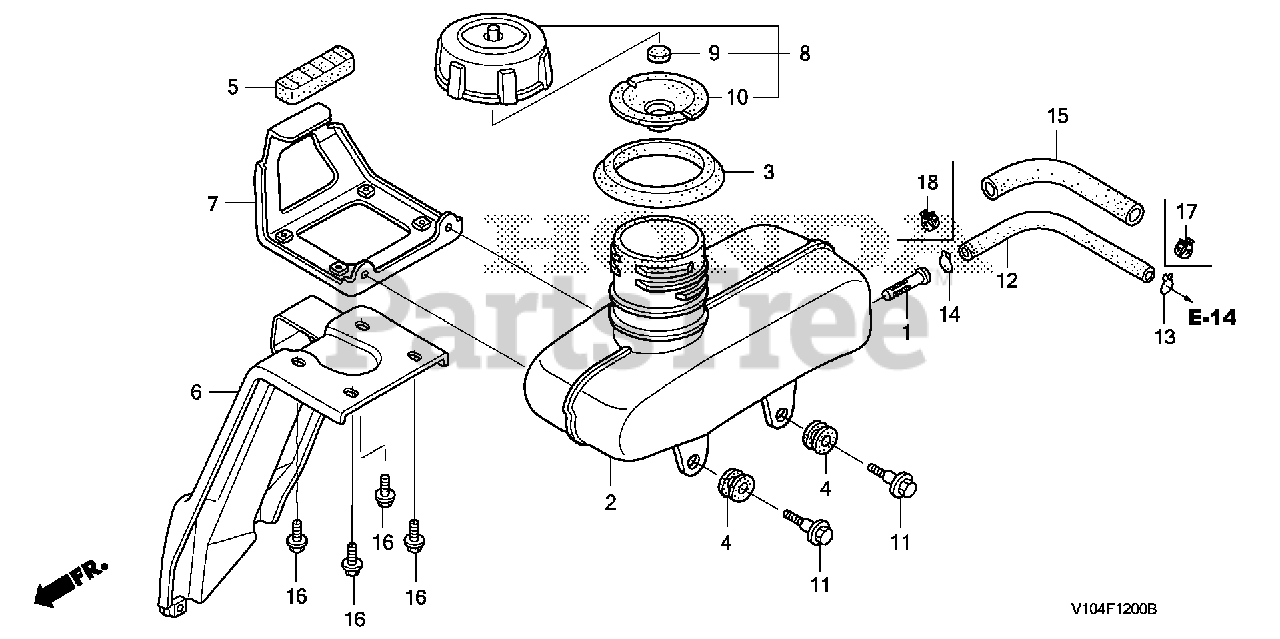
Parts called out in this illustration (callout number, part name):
1	FILTER, FUEL
2	TANK, FUEL
3	SEAL, FUEL FILLER NECK
4	RUBBER A, TANK MOUNTING
5	RUBBER B, TANK MOUNTING
6	BRACKET A, FUEL TANK
7	BRACKET B, FUEL TANK
8	CAP ASSY., FUEL TANK
9	SPONGE, FUEL CAP BREATHER
10	GASKET, FUEL CAP
11	BOLT, SPECIAL (6MM)
12	TUBE, FUEL TANK
12	TUBE, FUEL TANK (FKM) (NA USE ALT:17701-ZL8-000)
13	CLIP, TUBE (B10)
14	CLIP, TUBE (C11)
15	BULK HOSE, VINYL (13X15X8000) (13X15X90)
16	BOLT, FLANGE (6X10)
17	CLAMP, TUBE (D10)
18	CLAMP, TUBE (D12)
